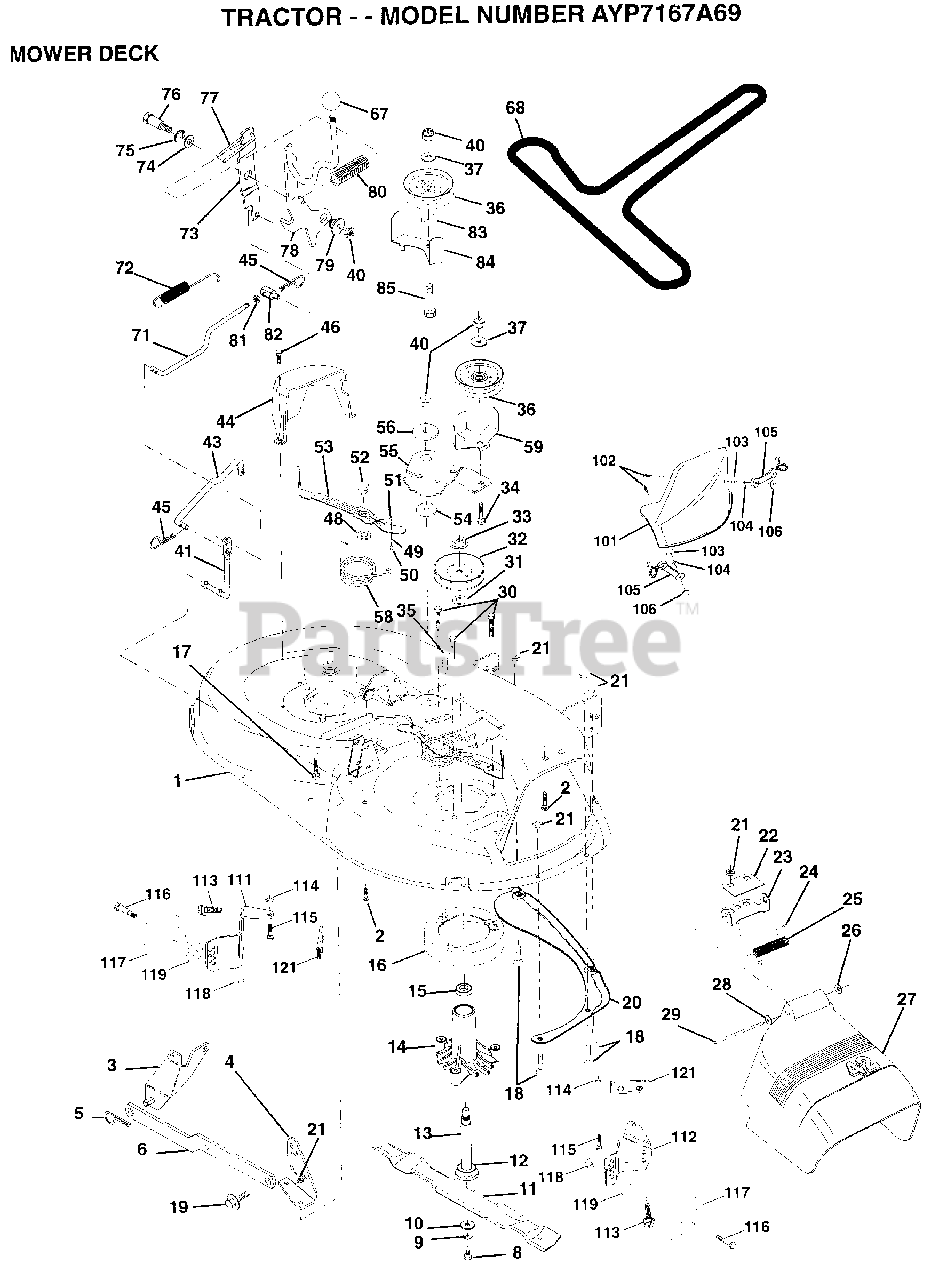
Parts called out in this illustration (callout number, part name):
1	DECK.WELD.42.
2	BOLT
3	BRKT ASM SWAY BAR
4	BRKT DECK SW BAR
8	BLADE BOLT
10	WASHER.HARD.BLADE
11	"BLADE.42"" MULCHER"
12	BEARING.BALL
14	HSG ASM MANDREL
15	BEARING
16	STRIPPER RND MWR
17	BOLT RDHD 3/8-16
18	BOLT
19	BOLT SHD 5/16-18
22	STIFFENER BRKT
23	DEFLECTOR BRKT
24	CAP-SLEEVE LT
25	SPRING TORSION
26	NUT PUSH M
27	DEFLECTOR.SHIELD
28	WASHER
29	HINGE ROD
31	WASHER
34	BOLT
35	XMAS TREE FASTNER
36	FLAT IDLER PULLEY
37	WASHER
41	PIVOT ROD
43	ROD CLUTCH W/NIBS
44	GUARD MAND LH BLK
45	RETAINER M
46	SCREW.1/4-20X5/8
48	HARD SMALL WASHER
50	SHOULDER BOLT
51	LOCKNUT
52	BOLT.SHLD.5/16-18
53	BRAKE PAD ARM ASM
54	HARDENED WASHER
56	SPACER RETAINER
58	SPRING TORSN BRAK
59	GUARD IDLER TUV
67	KNOB T (1/2-HOLE)
68	BELT.V.T-PATH
71	ROD CLUTCH 38/42
72	RETURN SPRING
73	CLUTCH ARM SECOND
74	WASHER
75	RING
76	SHOULDER BOLT
77	SPRING KEEPER
78	LEVER ASM CLT PRM
79	BUSHING
81	NUT
82	TRUNION ADJ
83	WASHER
85	BOLT
101	"COVER.MULCH.42"""
102	SCREW
103	WASHER #10
104	LOCKWASHER
106	WELDNUT
113	SCREW
116	BOLT.SHOULDER
117	WHEEL GAGE DONUT
118	LOCKNUT
119	WASHER
121	BRACKET.EXTRD.GWL
